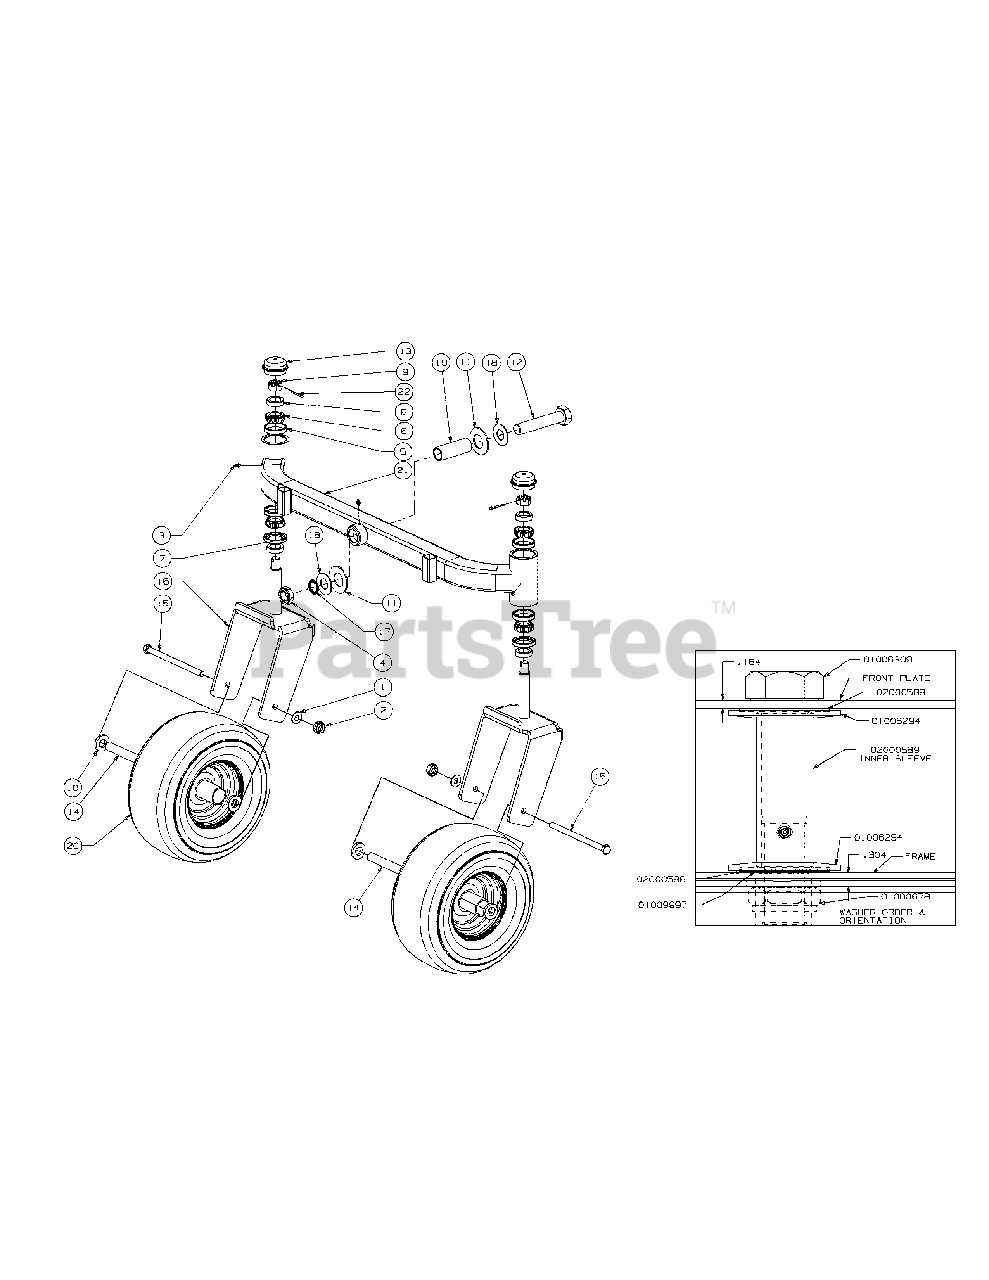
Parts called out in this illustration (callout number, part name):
1	Washer, 1/2 x 1 Shim
2	Nut, 1/2-20, Center Lock
3	Grease Fitting, 1/4-28 x 3/16
4	Nut, Jam, 1.0-14, Insert Lock
5	Cup Bearing
6	Bearing Cone
7	Seal
8	Ring Seal
9	Slotted Nut, 3/4-16
10	Spacer, .812 ID x .218LG
11	Bell Washer, 1.25 ID x 2.5 x .157
12	Hex Cap Screw, 1-14 x 5.0
13	Grease Cap, 1.986 OD
14	Wheel Spacer
15	HHCS, 1/2-20, 7.50
16	Yoke, Caster Wheel
17	Retainer Extension, Self Locking
18	Flat Washer, 1.00 ID
19	Spacer, 1.005 ID x 1.25 OD x 3.6
20	Wheel, 13 x 6.50 x 6.0, Beige, includes:
20	Roller Bearings (per tire)
20	Retainer Bushings (per tire)
21	Front Axle Assembly
22	Cotter Pin, 5/32, 1.25
